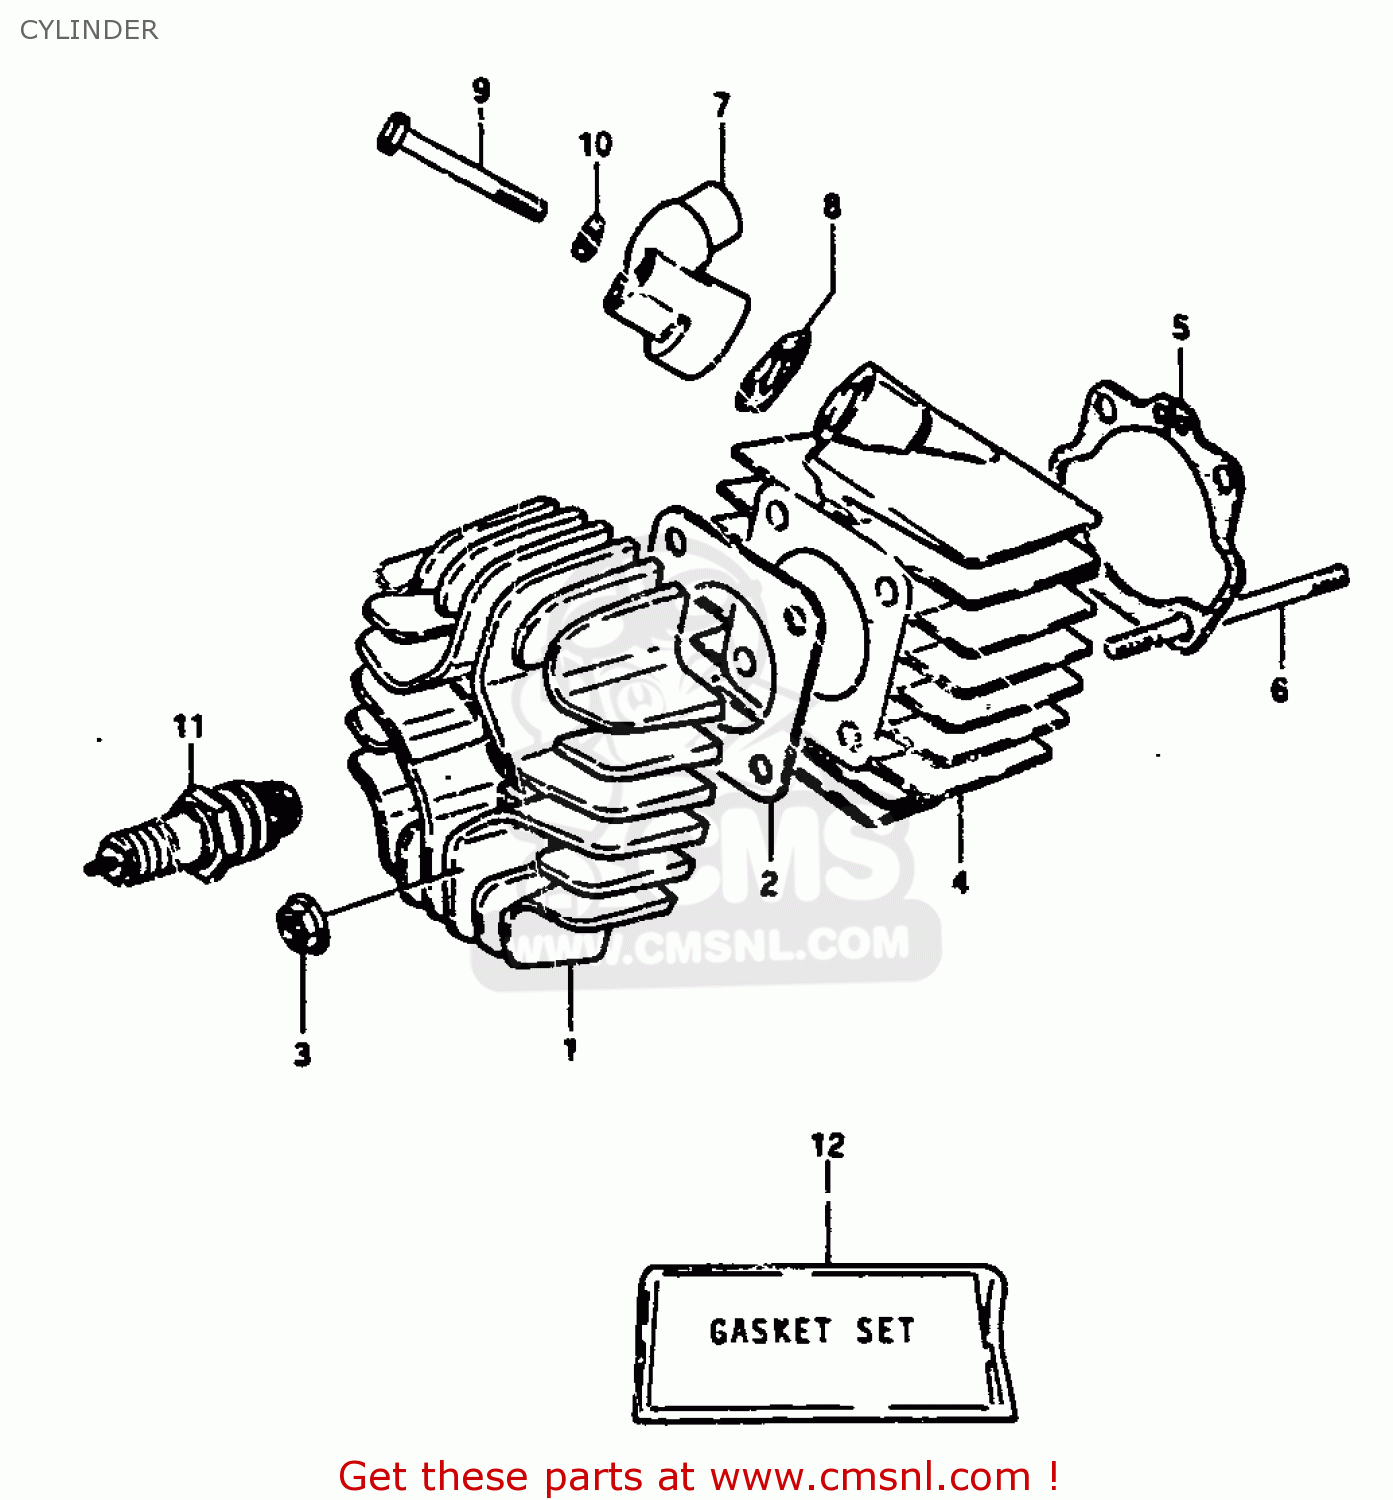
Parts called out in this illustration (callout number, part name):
1	HEAD,CYLINDER
2	GASKET,CYLINDER HEAD (NAS)
3	NUT
4	CYLINDER
5	GASKET,CYLINDER (MCA)
6	STUD BOLT
7	PIPE,INTAKE
8	GASKET (NAS)
9	BOLT
10	WASHER,LOCK
11	PLUG,SPARK(BP4H)
12	GASKET SET (MCA)
